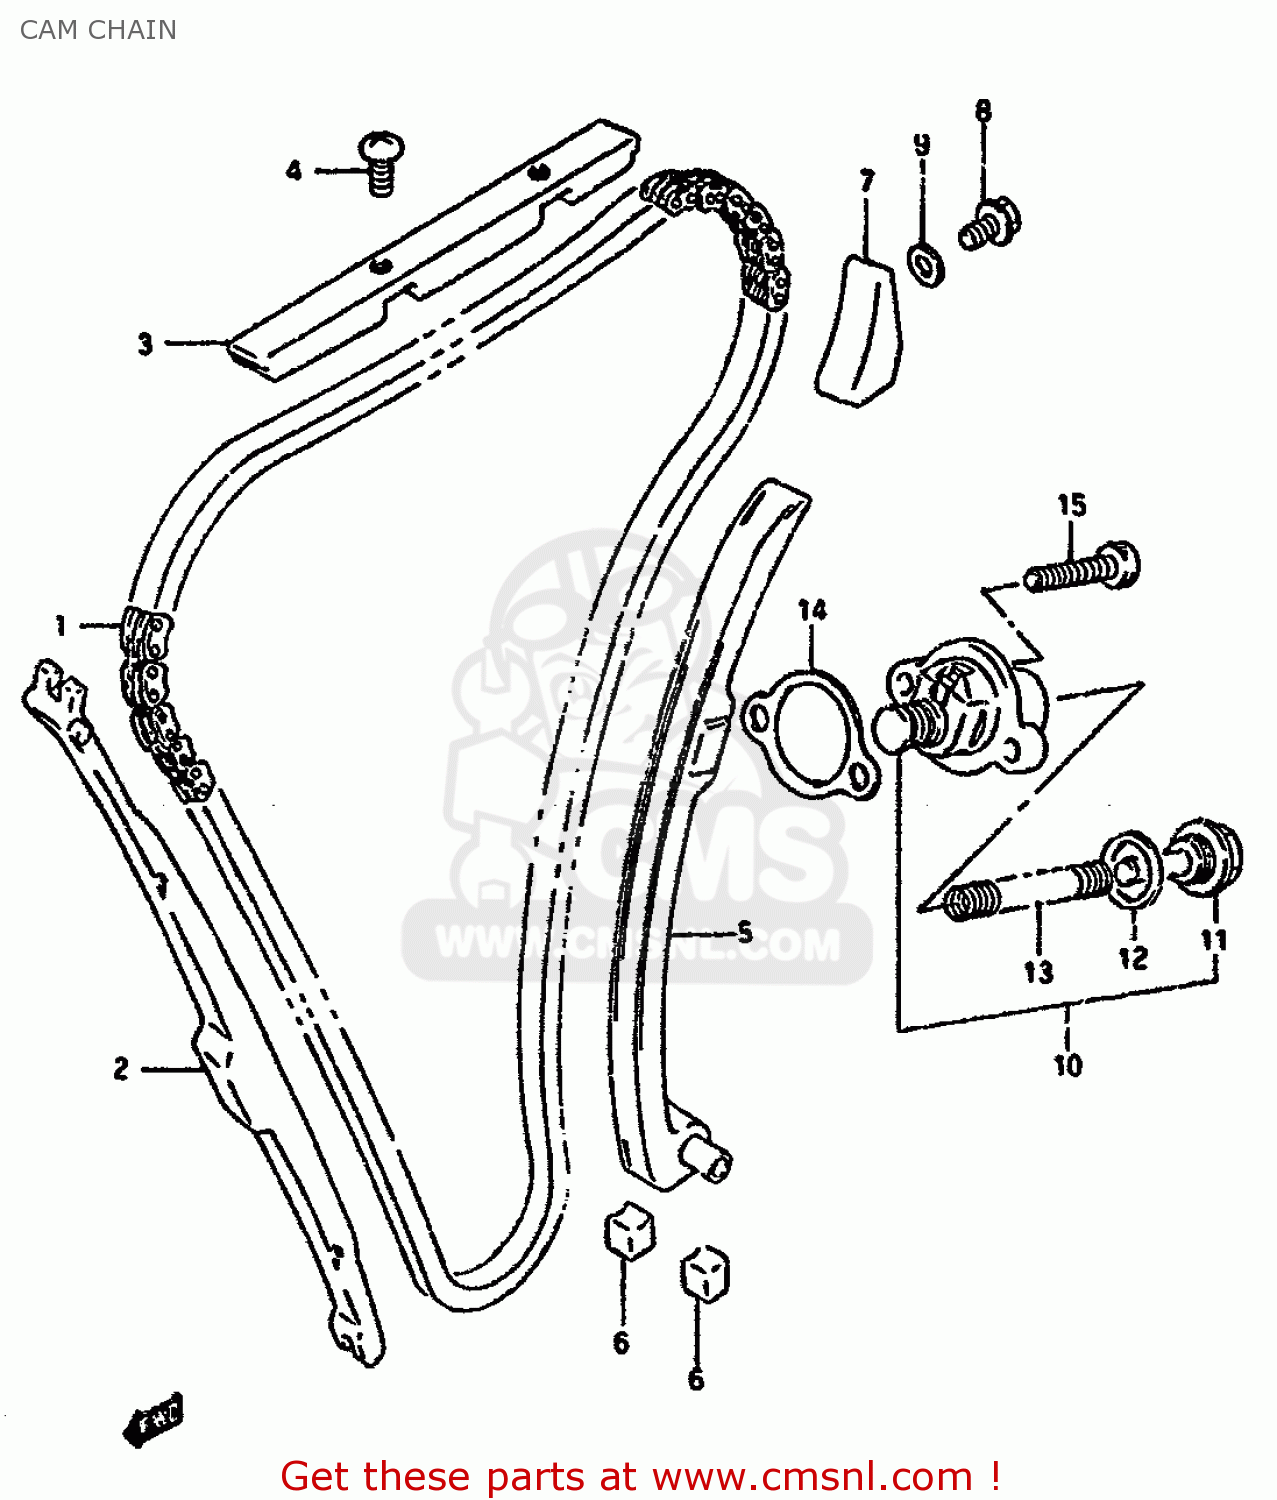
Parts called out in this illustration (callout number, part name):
1	CHAIN,CAMSHAFT DRIVE
2	GUIDE,CAM CHAIN NO.1
3	GUIDE,RR CAM CHAIN NO.1
4	SCREW
5	TENSIONER,CAM CHAIN
6	CUSHION,CAM CHAIN TENSIONER
7	GUIDE,CAM CHAIN NO.2
8	BOLT
9	GASKET(5.8X13X1.2) (NAS)
10	ADJUSTER ASSEMBLY,TENSIONER
11	PLUG
12	GASKET (NAS)
13	SPRING
14	GASKET,TENSIONER ADJUSTER (NAS)
15	BOLT
